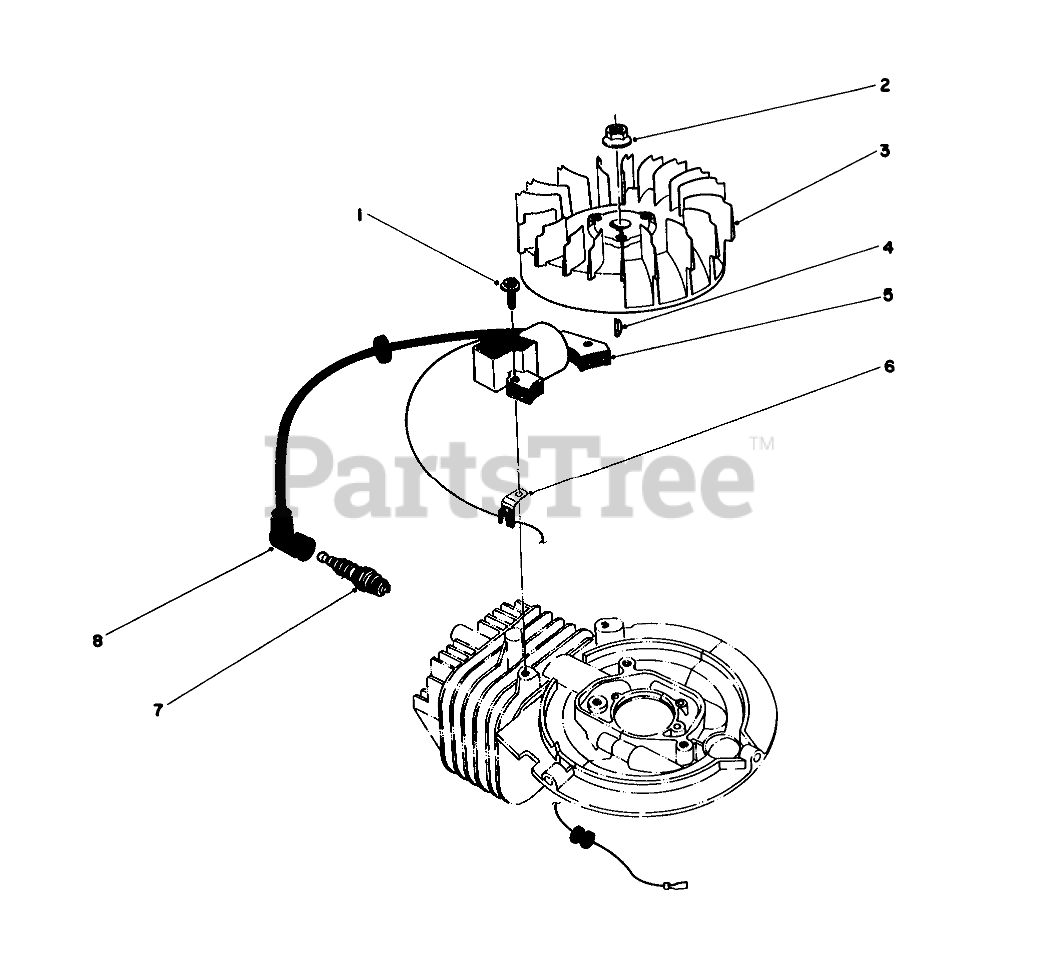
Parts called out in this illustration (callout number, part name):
3	FLYWHEEL
6	CLAMP
8	CAP-SPARKPLUG
